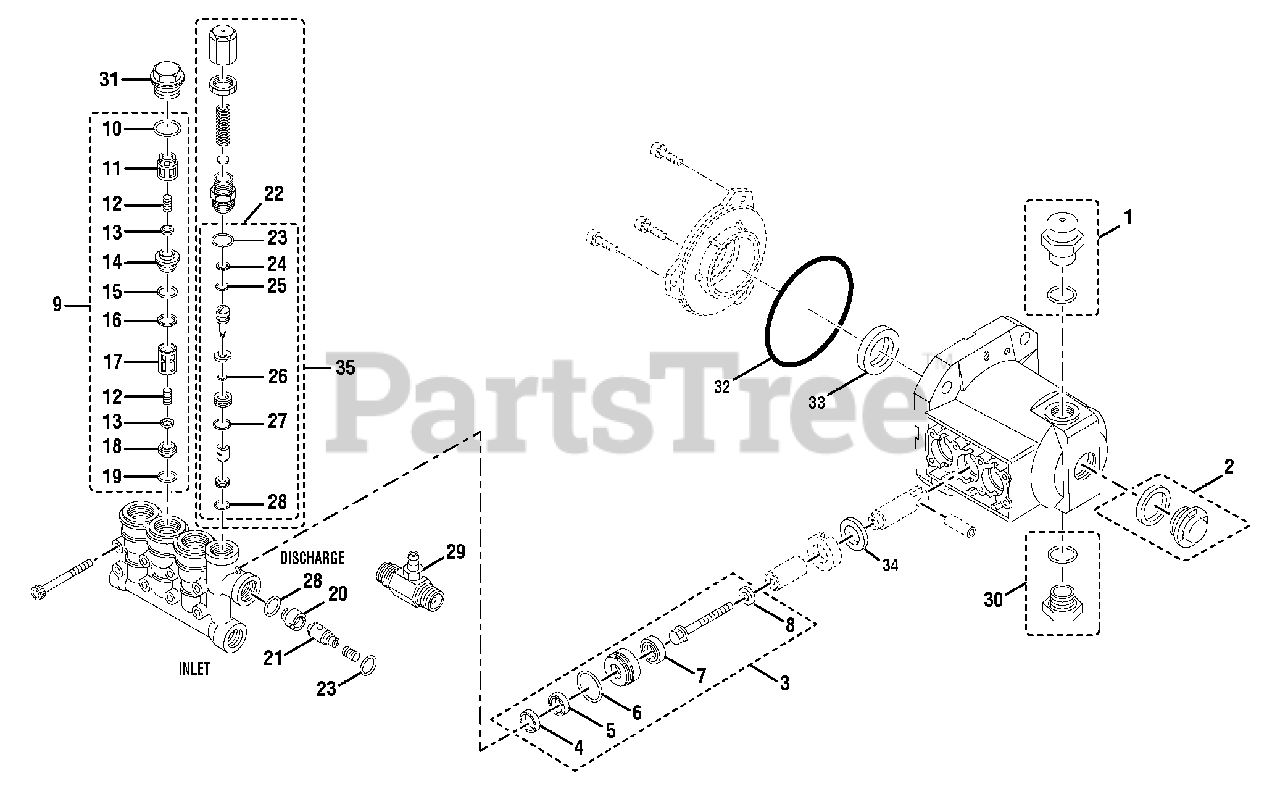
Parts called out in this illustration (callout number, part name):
1	Oil Fill Cap w/O-ring
3	Seal Kit
4	Adapter (Male)
5	V-Packing
6	Seal Case O-Ring
8	Washer (Seal)
9	Valve Assembly
10	O-Ring (Plug)
11	Spring Retainer
14	Discharge Seat
15	O-Ring (Discharge Seat)
16	O-Ring (Discharge Seat)
17	Spring Retainer (Inlet)
18	Inlet Seat
19	O-Ring (Inlet Seat)
20	Check Valve Seat
22	O-Ring Kit
23	O-Ring (Piston Retainer)
24	Back-up-Ring (Piston Stem)
25	O-Ring (Piston Stem)
26	O-Ring (Inner Valve Retainer)
27	O-Ring (Outer)
28	Seat O-Ring
29	Fixed Injector (M18 x 1 mm)
30	Drain Plug
31	Plug
35	Unloader Assembly
